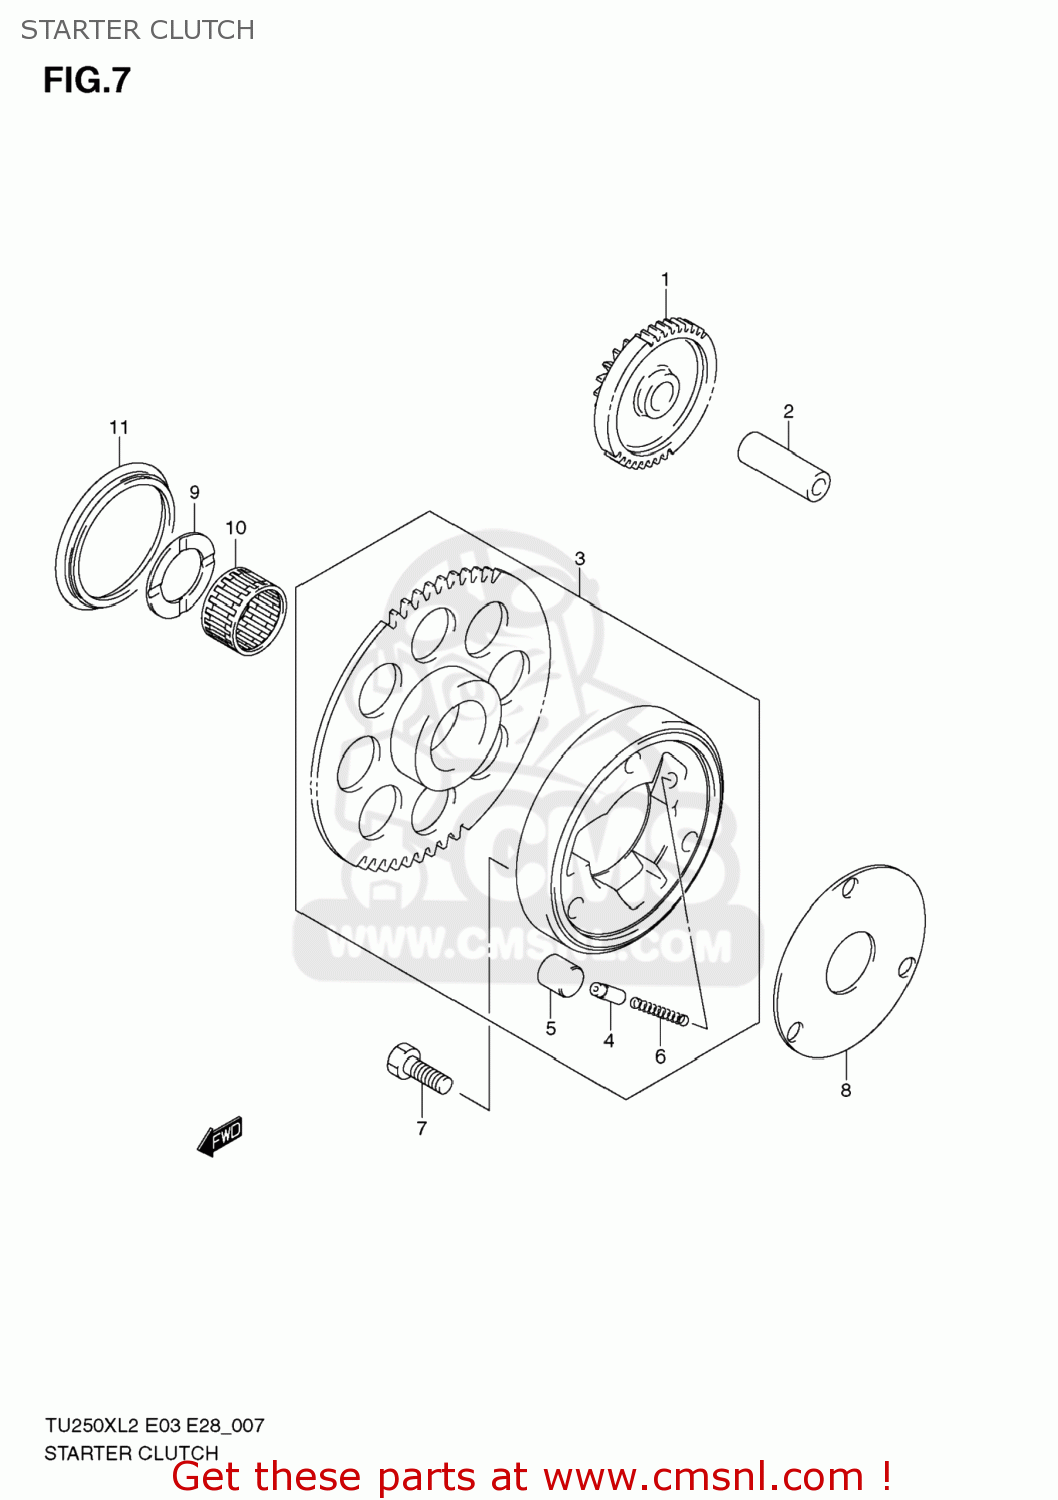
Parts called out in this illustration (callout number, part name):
1	GEAR,STARTER IDLE
2	PIN(7.4X13X40)
3	CLUTCH SET,STARTER
4	PIECE,PUSH
5	PIN(14X13)
6	SPRING
7	BOLT(8X20)
8	SHIM,STARTER CLUTCH HUB
9	WASHER(27X40X2.5)
10	BEARING(27X32X21.8)
11	SEAL,OIL(52X62X6.8)
